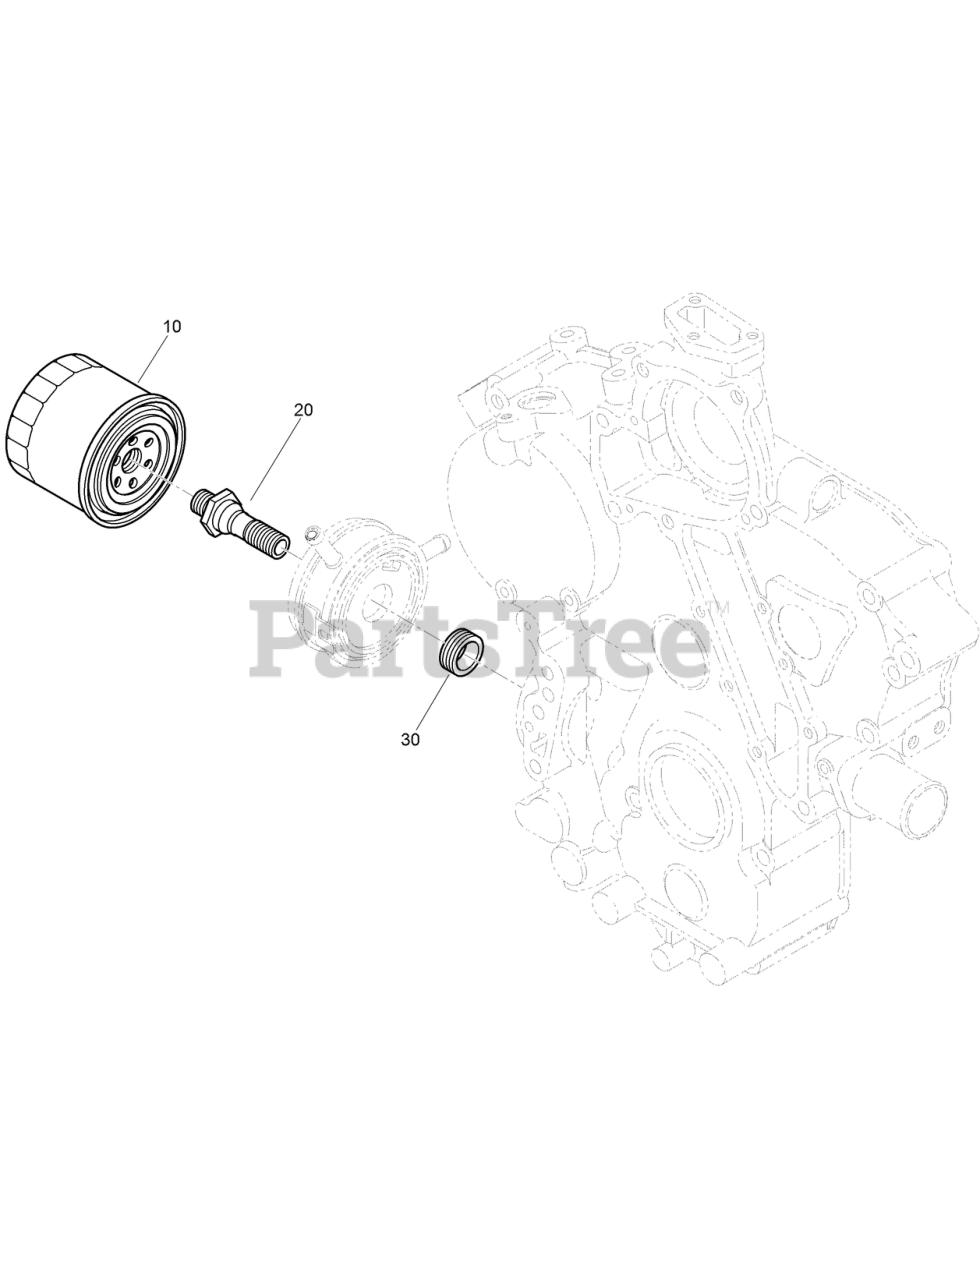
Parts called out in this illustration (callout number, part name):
10	FILTER-OIL
20	CONNECTOR
30	COLLAR
